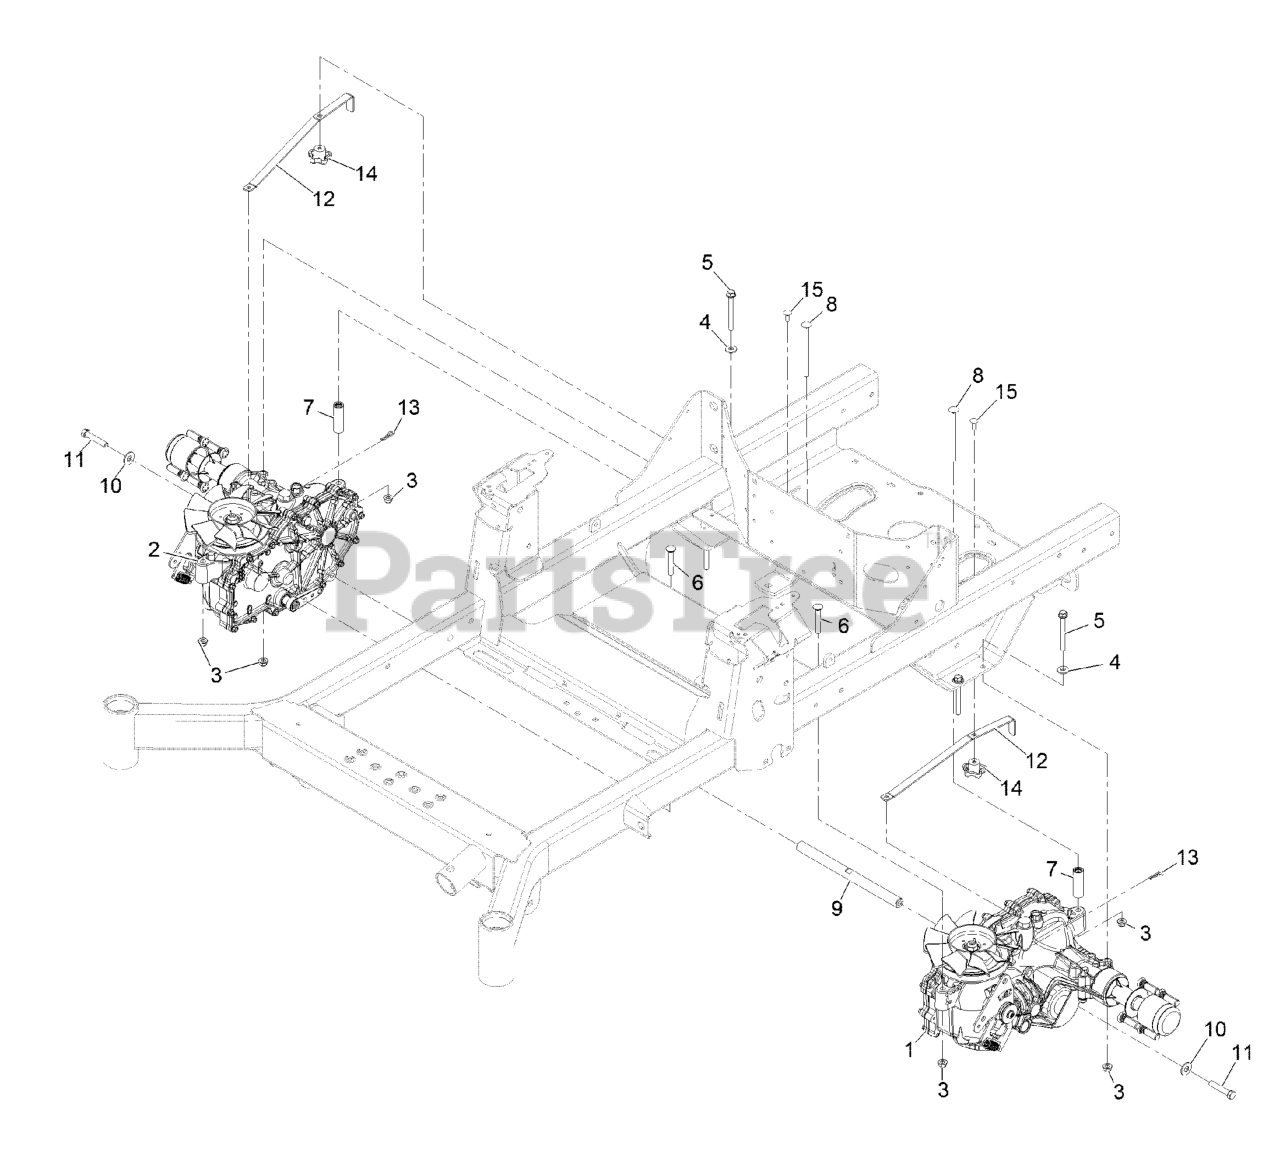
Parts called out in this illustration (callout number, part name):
1	TRANSAXLE ASM
2	TRANSAXLE ASM
3	NUT-HF, NI
4	WASHER-SPRING
5	SCREW-HHF
6	BOLT-CARR
7	SPACER, HYDRO
8	Bolt-Carriage 5/16-18 X 1 1/4
9	SHAFT-SPACER
10	WASHER-FLAT
11	SCREW-HH W/LOCTITE
12	ARM-BYPASS, HYDRO
13	PIN-COTTER
14	KNOB-HANDLE
15	BOLT-CARR
